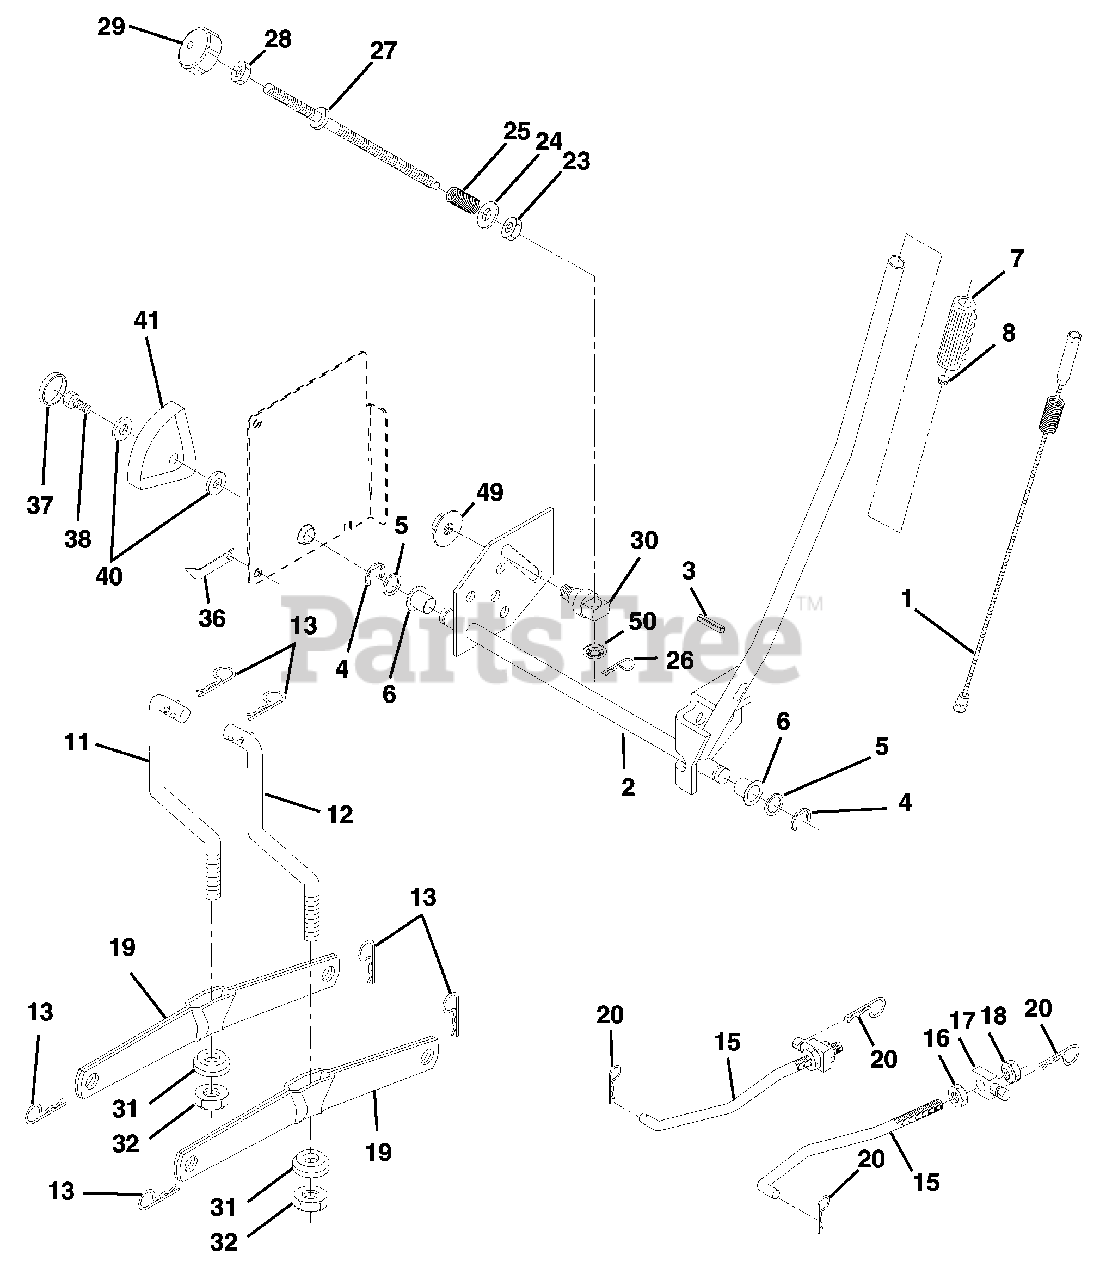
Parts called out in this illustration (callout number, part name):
1	Washer Asm Inner Spring W/Plunger
2	Shaft Asm. Lift
3	Pin Groove
4	E Ring #5133-62
5	Washer 21/32 x 1 x 21 Ga.
6	Bearing Nylon
7	Grip Handle
8	Button Plunger Black
11	Link Asm Lift L.H.
12	Link Asm Lift R.H.
13	Retainer Spring
15	Link Front
16	Nut Jam Hex 1/2-13 Unc
17	Trunnion Blk Zinc
18	Nut Lock W/Wsh 1/2-13 Unc
19	Arm Suspension Mower
20	Retainer Spring
23	Nut Special
24	Washer 13/32 x 5/8 x 16 Ga.
25	Spring 2-1/8
26	Retainer Clip
27	Rod Adj Lift Zinc
28	Nut Hex Jam 3/8-16 Unc
29	Knob Inf 3/8-16 unc
30	Trunnion Infin Height
31	Bearing, Pvt. Lift. Spherical
32	Nut Crownlock 3/8-24
36	Pointer Height Indicator
37	Plug Hole Blk
38	Screw 5/16-18 x 1
40	Washer 11/32 x 1-1/2 x 10 Ga
41	Scale Ind Height Blk
49	Nut Hex flange lock
50	Nut Push Phos & Oil
